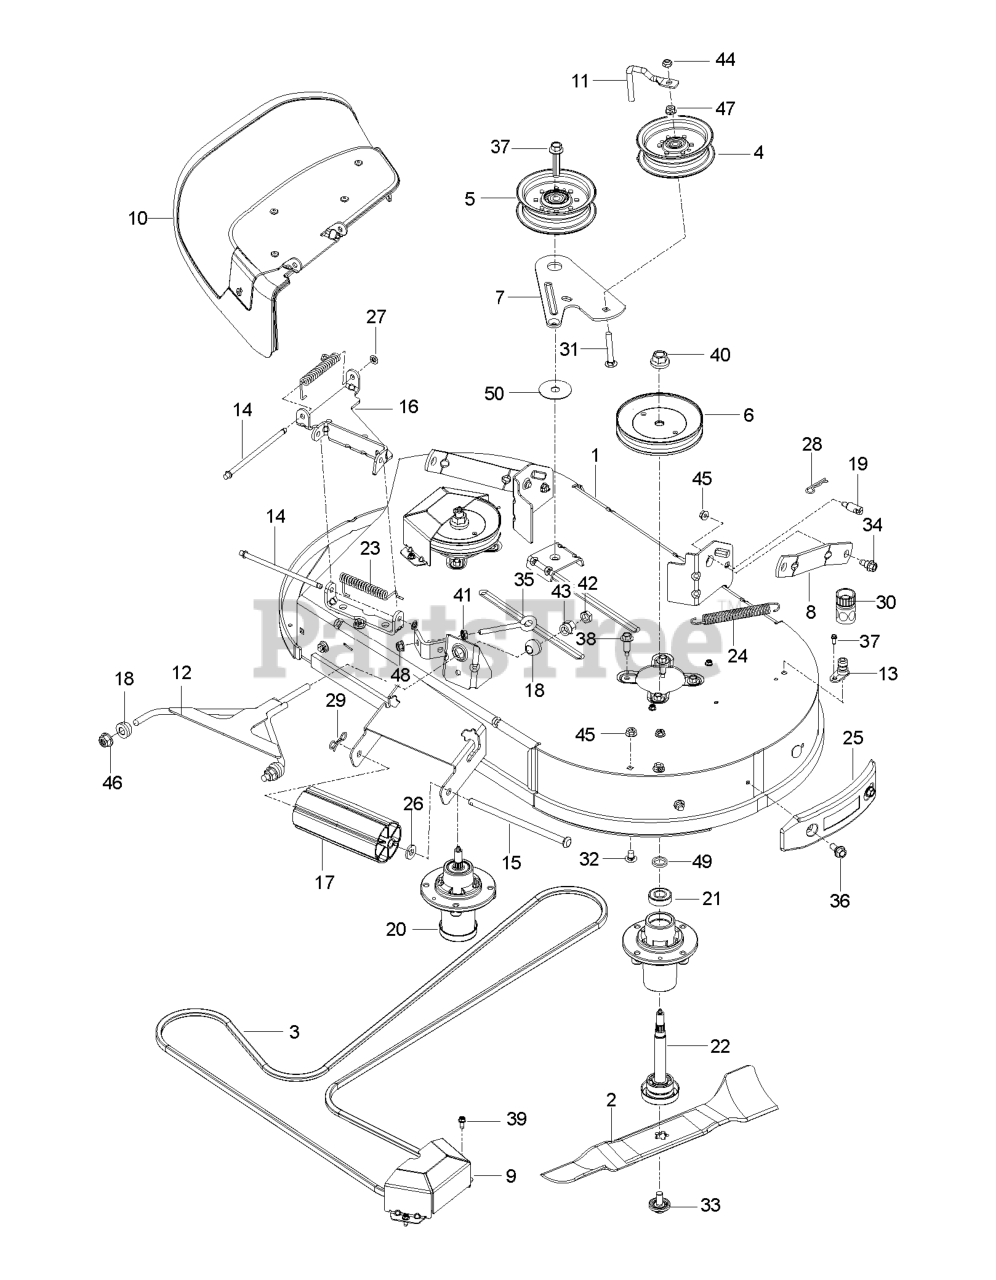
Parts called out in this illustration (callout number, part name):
1	HOUSING.ASM.PNT.42.WELL.ZTR
2	BLADE.42.FCS.BAGGING.BLADE.RAW
3	BELT.42.FCS.ZTR.DECK.DRIVE
4	PULLEY.IDLER.2006
5	PULLEY.IDLER.MWR.STATI.LH
6	PULLEY MANDREL 5.0"
7	ARM.42"FCS.CLUTCHING.X431
8	ARM.RFIXED.MOWER.SUSPNSIONX431
9	COVER.42".MANDREL.FCS.PNT.498
10	DEFLECTOR.ASM.42.FCS.ORANGE
11	KEEPER.BELT.IDLER.54"T
12	LINK.RZ.FRONT.WELDMENT.E-DIP
13	PORT.WASHOUT
14	ROD.HINGE
15	ROD.ROLLER.NOSE.NARROW.48"
16	BRACKET.42".FCS.DBLE.HINGEX668
17	NOSE ROLLER 48"
18	BUSHING SPHERICAL SUSP. FRONT
19	STUD.FASTNER.W/ANTI-ROTATE
20	MANDREL ASM, CAST IRON
22	SHAFT ASM MANDREL
23	SPRING.42.FCS.DEFLECTOR
24	SPRING.MOWER.DRIVE.ELECTRIC
25	BUMPER.42CC.TRIM.SIDE.ASSY.HUS
26	BUSHING.NOSE.ROLLER
27	NUT PUSH M
28	HAIRPIN #4
29	PIN.COTTER.5/16.BOW TI
30	COUPLING.QUICK CONNECT
32	CARRIAGE BOLT 5/16C X 5/8"
33	BOLT.WASHER.ASM.7/16-2
34	BOLT.SHOULDER
35	EYE BOLT 5/16 X 3.50
36	SHOULDER BOLT 5/16-18TT
37	SCREW.7/16-14 X 2.125.WASHER
38	BOLT.HEX.WASHR.HED.313-18X1.19
39	SCREW.1/4-20X5/8
40	NUT.FLANGE.LOCK.TOP
41	NUT 5/16C WHIZ
42	NUT **
43	NUT, LIFT LINK 7/16-20
44	NUT LOCK FLG 3/8-16 UNC
45	NUT LOCK HEX FLANGE 5/16-18
46	7/16-14 HEX NUT W/NYL RING ZD
48	5/16-18 NYLOC FLANGE NUT
49	WASHER.SPACER.MANDREL
